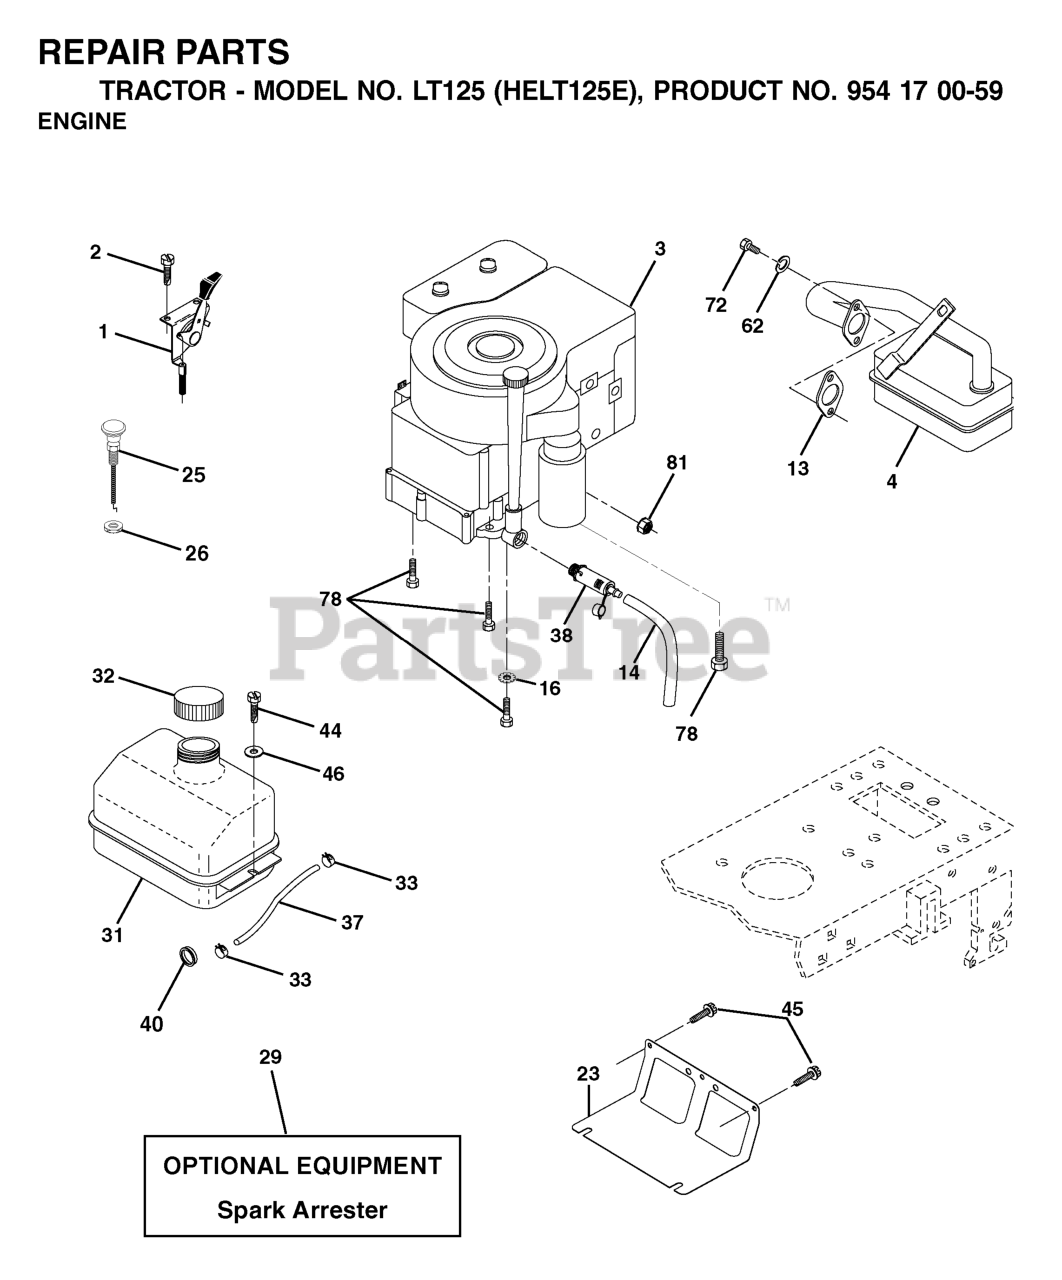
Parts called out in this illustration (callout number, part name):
1	CONTROL.THROTTLE/CHOKE.BLACK
2	SCREW
4	MUFFLER.SINGLE.B&S.10-12HP
13	REPL BY 532 27 22-93
14	TUBE, DRAIN OIL ASM.
16	LOCKWASHER
23	SHIELD.BROWNING.DBR.GUARD
26	Nut Keps 3/8 - 24 UNF
29	KIT.SPARK ARRESTOR 794945 B&S
31	TANK FUEL LT
32	FUEL CAP
33	HOSE CLAMP
37	LINE.FUEL.20
38	PLUG, OIL DRAIN EASY
40	BUSHING.SNAP.NYL.BLK.
44	SCREW HEXWSHR 1/4-20X3/4
45	SCREW, 3/8-16X3/4
62	WASHER.LOCK.HVY.HLCL.SPR.5/16
72	SCREW
78	SCREW.3/8-16
81	NUT
